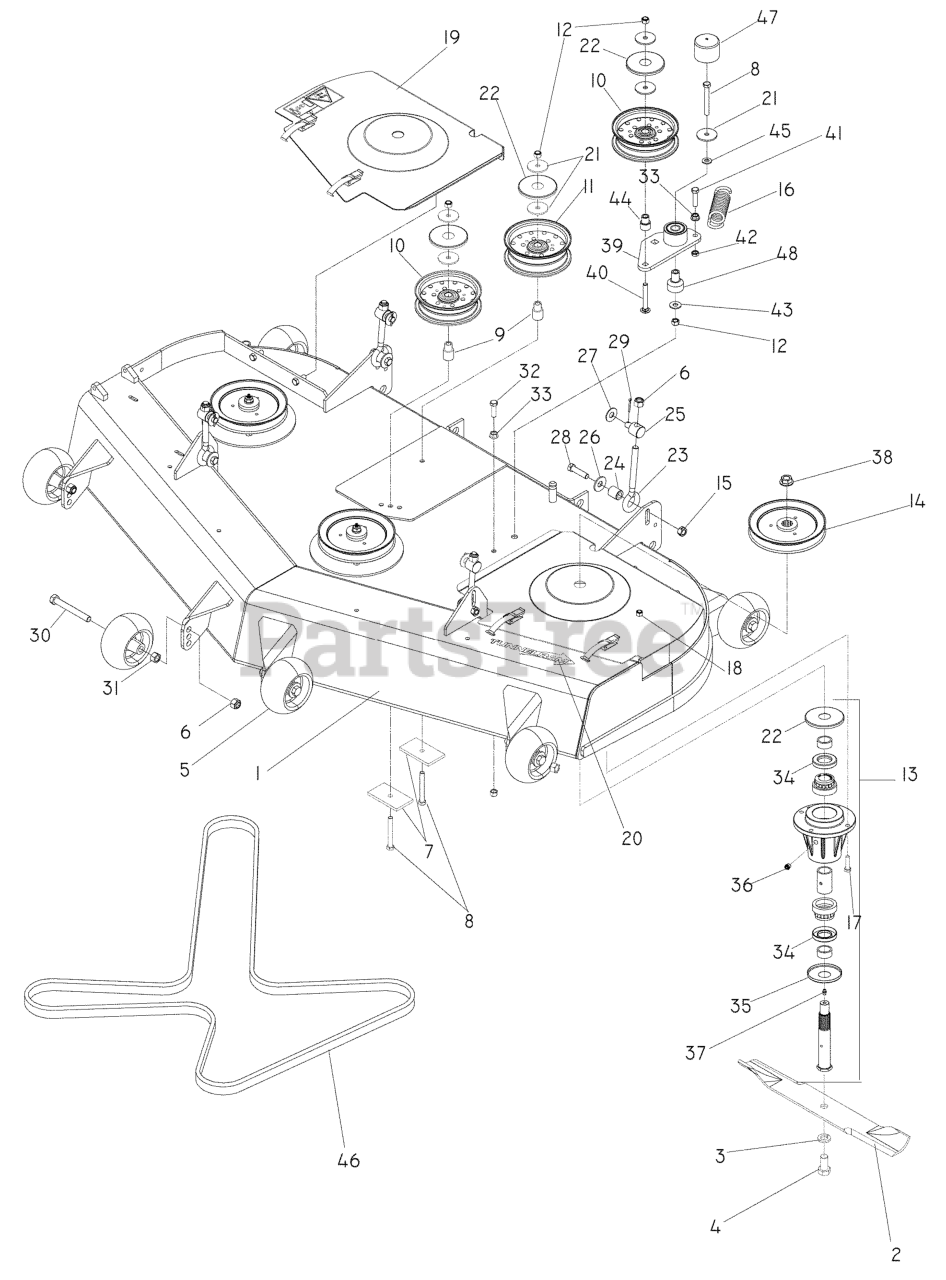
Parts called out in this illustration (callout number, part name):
1	DECK W/DECALS 61" HUS
2	BLADE OEM 21" (61" DECK)
3	LOCKWASHER 5/8
4	HCS 5/8F X 1 1/4
5	GAUGE WHEEL
6	NUT 1/2-13 HEX NYLOC ZD
7	SUPPORT PLATE
8	HCS 3/8C X 3
9	IDLER BUSHING
10	IDLER PULLEY
11	IDLER PULLEY (TALL)
12	NUT 3/8-16 NYLOC
13	HSG KIT 52/61 RIBBED
14	PULLEY, 61
15	NUT 7/16C CENTERLOCK
16	DECK SPRING
17	HCS 5/16C X 1 1/4
18	NUT 5/16 NYLOC
19	61 BELT SHIELD ASM - RH
20	DECAL, TUNNEL RAM 8"
21	WASHER, 3/8 SPEC
22	TOP DUST CAP
26	SPRING WASHER - .50
27	WASHER 1/2 FLAT
28	HCS 7/16 - 14 X 1 3/4
29	PIN COTTER 1/8 X 1 ZD
30	HCS 1/2-13 X 4 GR 5 ZD
31	NUT HEX 1/2
32	HCS 3/8C X 1 1/4 GR5
33	NUT 3/8C WHIZ
34	SHAFT SEAL
35	BOTTOM DUST CAP
36	PLUG-VENTED
37	ZERK
38	NUT FLANGE 3/4-16
39	ARM-IDLER W/BRG
40	RHSNB 3/8-16 X 2.75
41	HCS 3/8-16 X 1-1/2
42	NUT 3/8-16 HEX JAM
43	WASHER 3/8 FLAT
44	BUSHING, IDLER
45	WASHER 3/8 SAE FLAT
46	DECK BELT 61
47	CAP, VINYL
48	PIVOT, BEARING
